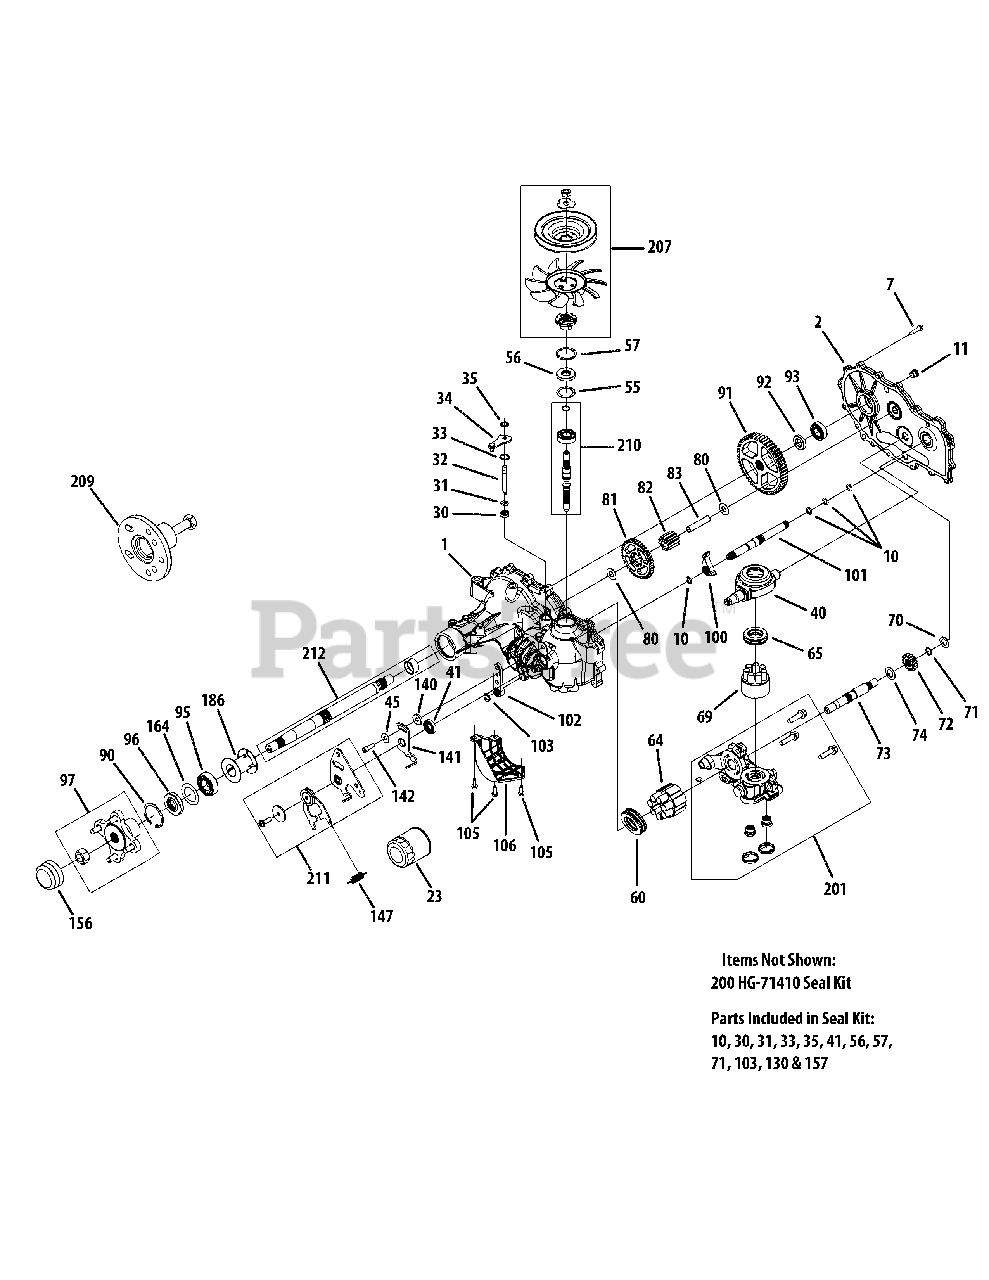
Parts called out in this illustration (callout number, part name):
1	Kit, Main Housing, RH Control
2	Kit, Side Cover, RH
7	Screw, Hex Washer
23	Filter, Spin-On 2.6 x 3.0
30	Seal, Lip, .375 x .75 x .25
31	Ring, Retaining .375 External
32	Rod, Bypass
33	Ring Retaining .750 Internal
34	Arm, Bypass
35	Ring, Ret .375 External
40	Trunnion, Swashplate
41	Seal, Lip 18 x 32 x 7
45	Washer, .34 x .88 x .06
55	Washer, 1.23 x 1.57 x .04
56	Seal, Lip 17 x 40 x 7
57	Ring Retaining Internal
60	Bearing, Thrust 35 x 62 x 18
64	Kit, 16cc Cylinder Block Assembly
65	Thrust Bearing, 30 x 52 x 13
69	Kit, Block, 7 Piston
70	Washer, .63 x 1.00 x .05
71	Ring, Reatining, Motor Shaft
72	Gear, 16T
73	Shaft, Motor
74	Washer, .71 x 1.16 x .04
81	Gear, 43T
82	Gear, 11T
83	Pin, Jackshaft
90	Ring, Retaining 2.25 Internal
91	Gear, 54T
92	Spacer, .750 x 1.00 x .257
93	Bearing, Ball 3/4 x 40mm x 12mm
95	Bearing, Ball 25.4 x 52 x 15
96	Seal, Lip, 1.0 x 2.06 x .38
97	Kit, Hub 4-Bolt
100	Pawl, Brake
101	Kit, Brake Shaft
102	Handle, Actuating
103	Ring, Retaining .438 External
105	Screw, Hex Washer 1/4-20 x .75
106	Guard, Filter, RH
140	Spacer, .320 x 1.005 x .150
141	Arm, Neutral Right
142	Socket Cap Screw, 5/16-24 x 7/8
147	Spring, Extension
156	Cap, Axle
164	Spacer, 1.355 x 2.035 x .021
186	Tube, Axle 2.03
200	Kit. Seal, ZT-2800
201	Kit, Center Section RH
207	Kit, Fan Pulley
207	Fan Only
207	Pulley Hub
209	Kit, Hub Puller
210	Kit, Input Shaft
211	Kit, RTN Bidirectional
212	Kit, Shaft Axle
